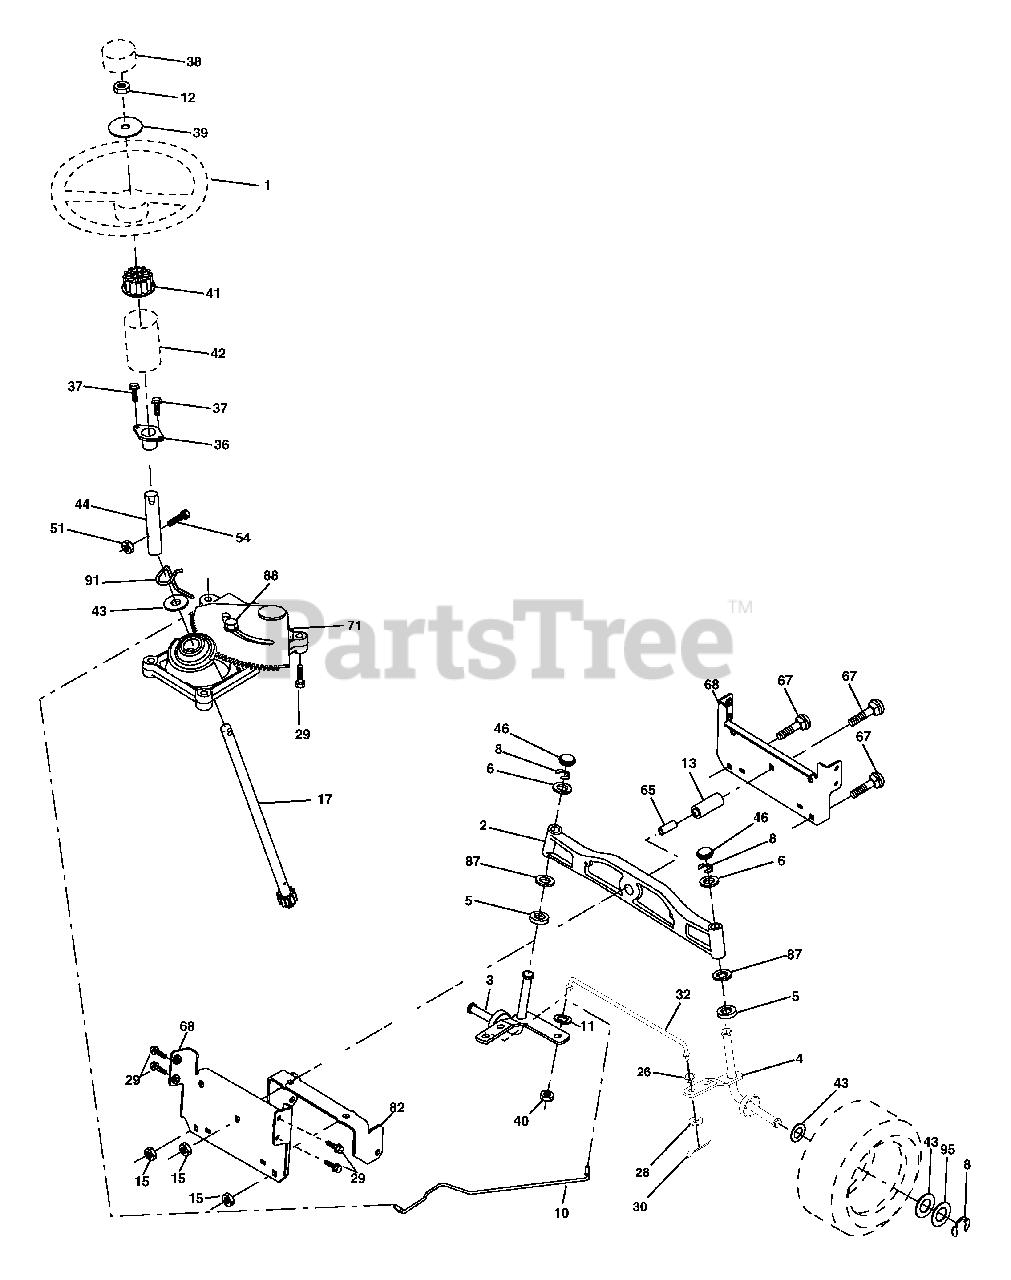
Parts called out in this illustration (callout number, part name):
1	Wheel Steering
2	Axle Asm Cast Iron LT
3	Spindle Asm LH
4	Spindle Asm RH
5	Bearing Race Thrust Harden
6	Washer 25/32 x 1-5/8 x 16 Ga.
8	Ring Klip #t5304-75
10	Link Drag
11	Washer Lock Hvy Hlcl Spr 3/8
12	Nut Hex Jam Toplock 1/2-20 unf
13	Spacer Brg Axle Front
15	Nut Hex Flange Lock
17	Shaft Asm Steering
26	Bushing Link Drag
28	Washer 13/32 x 7/8 x 16 Ga.
29	Screw 3/8-16 x .75
30	Pin Cotter 1/8 x 3/4
32	Rod Tie
36	Bushing Strg
37	Screw
38	Insert Cap Strg Wh
39	Washer 9/16 ID x 2-3/8 OD 12 Ga.
40	Crownlock nut
41	Adaptor Wheel Strg
42	Boot Steering Dash
43	Washer 25/32 x 1 1/4 x 16 Ga.
44	Extension Steering Shaft
46	Cap Spindle Fr Top Blk
51	Nut Crownlock 1/4-28
54	Bolt Hex 1/4-28 unf x 1-1/4 Gr. 8
65	Spacer Brace Axle
67	Bolt RDHD SQNK 3/8-16 x 2 1/4
68	Axle, Brace
71	Steering Asm
82	Bracket Susp Chassis Front
87	Washer Flat .781 x 1-1/2 x .14
88	Bolt Shoulder 7/16-20 unc
91	Clip Steering
95	Washer Harden .739 x 1.637 x 060
